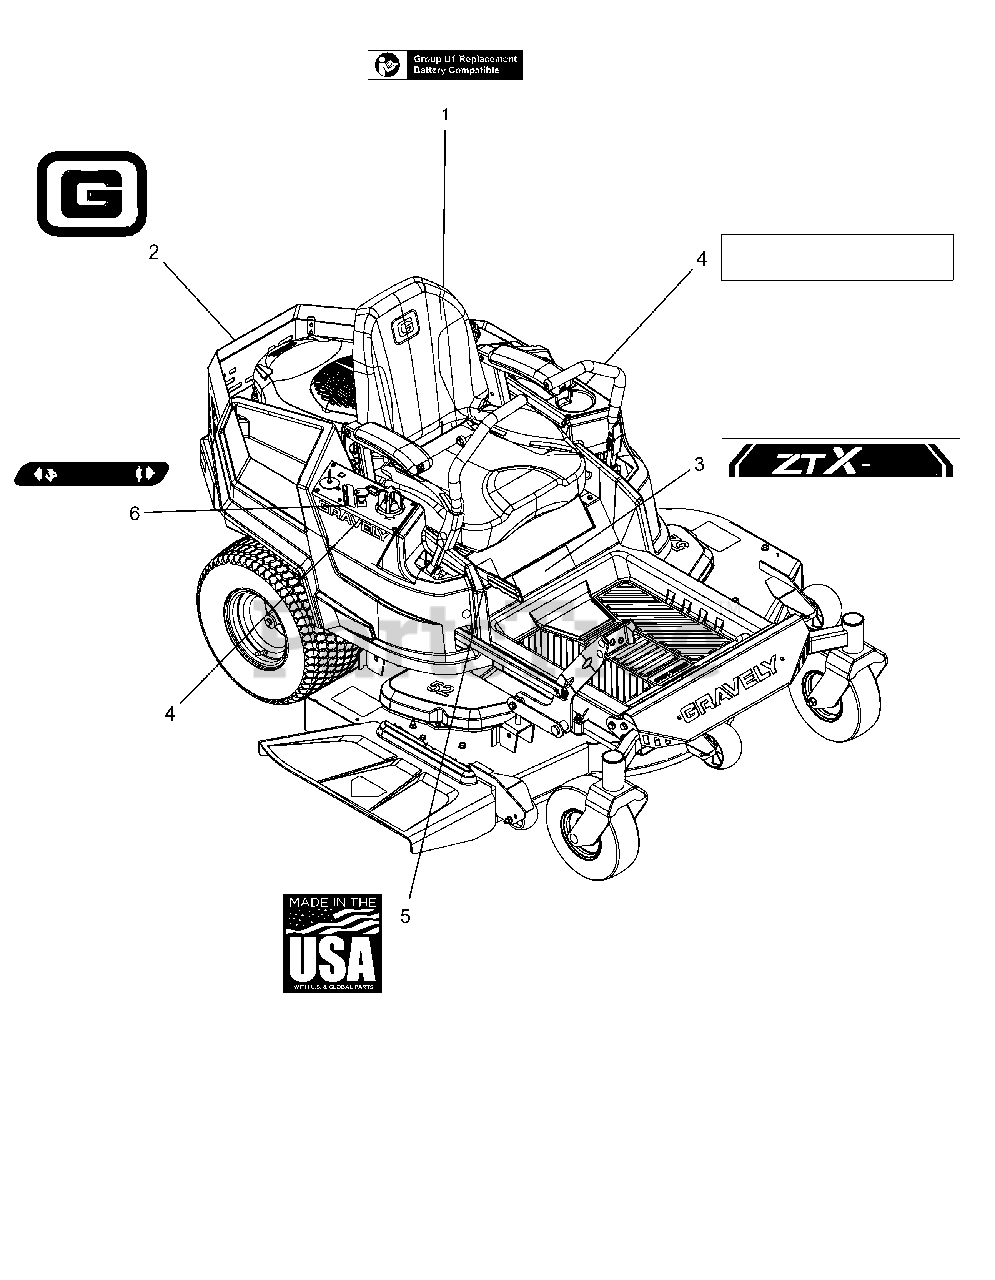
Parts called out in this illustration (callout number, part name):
1	DECAL, U1 BATTERY REPLACEMENT
2	DECAL, GRAVELY BRAND
3	DECAL, GRAVELY ZT X 52
4	DECAL, 9.5" GRAVELY LOGO
5	DECAL, MADE IN USA
6	DECAL, DASH DECAL
